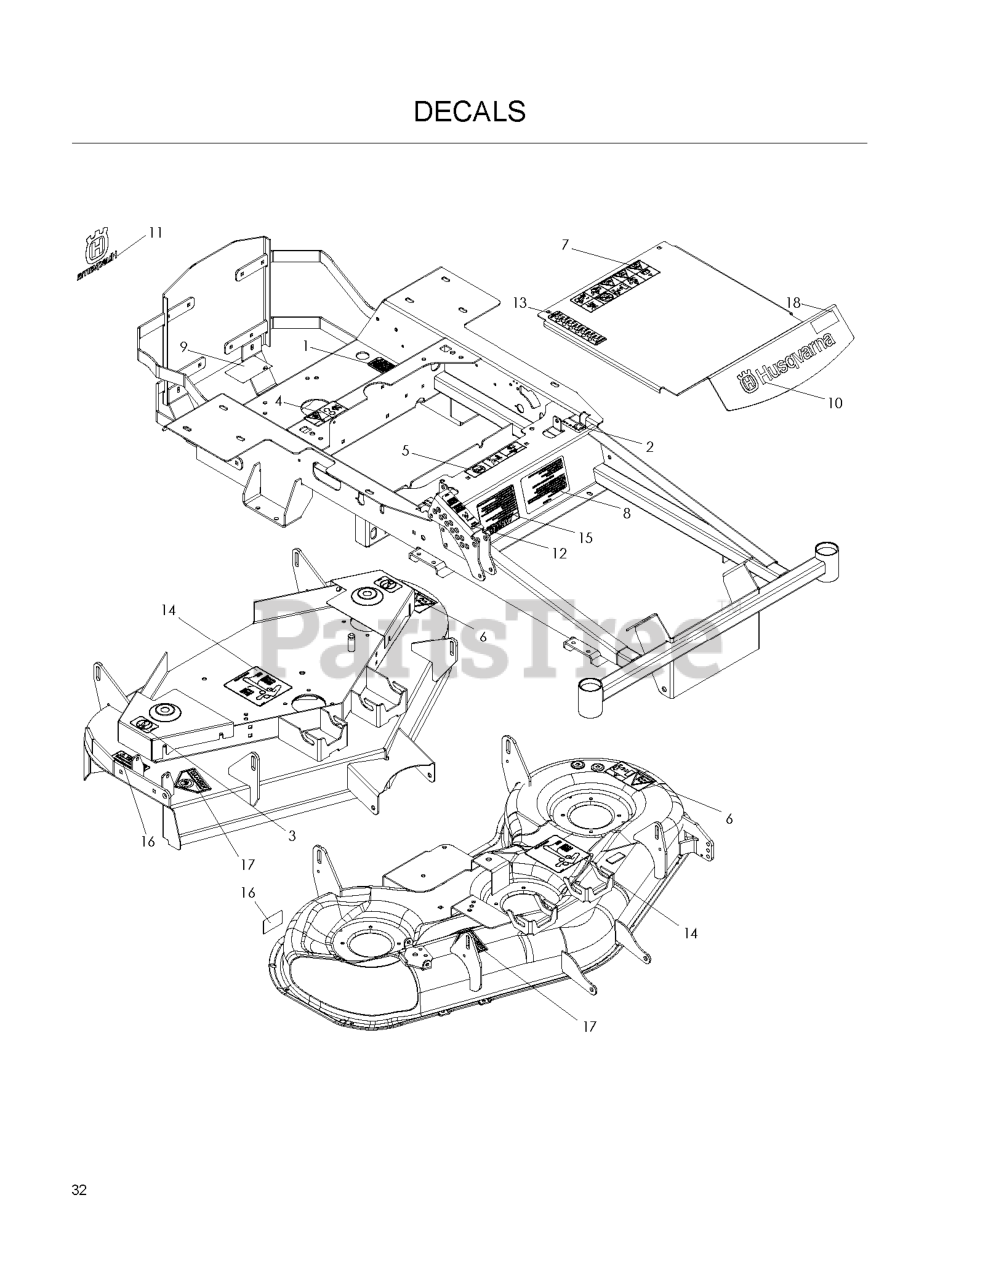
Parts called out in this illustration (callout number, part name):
1	DECAL, PROP. 65
2	DECAL, MOTION CONTROL
3	DECAL, NO STEP
4	DECAL, BELT DRIVE
5	EURO DECAL-BATTERY WARNIN6
6	DECAL, EURO SEVERING
7	DECAL, WARNING
8	DECAL, START
9	DECAL, DO NOT TOW
10	DECAL, HUSQ 12" BLUE
11	DECAL, CROWN H 5-1/4 SILVER
12	DECAL, TRANS RELEASE
13	DECAL, HEIGHT ADJUST
14	DECAL, BELT ROUTING
15	DECAL, WARNING
16	DECAL, CAUTION
17	DECAL, CPSC
18	DECAL, EZ4220
